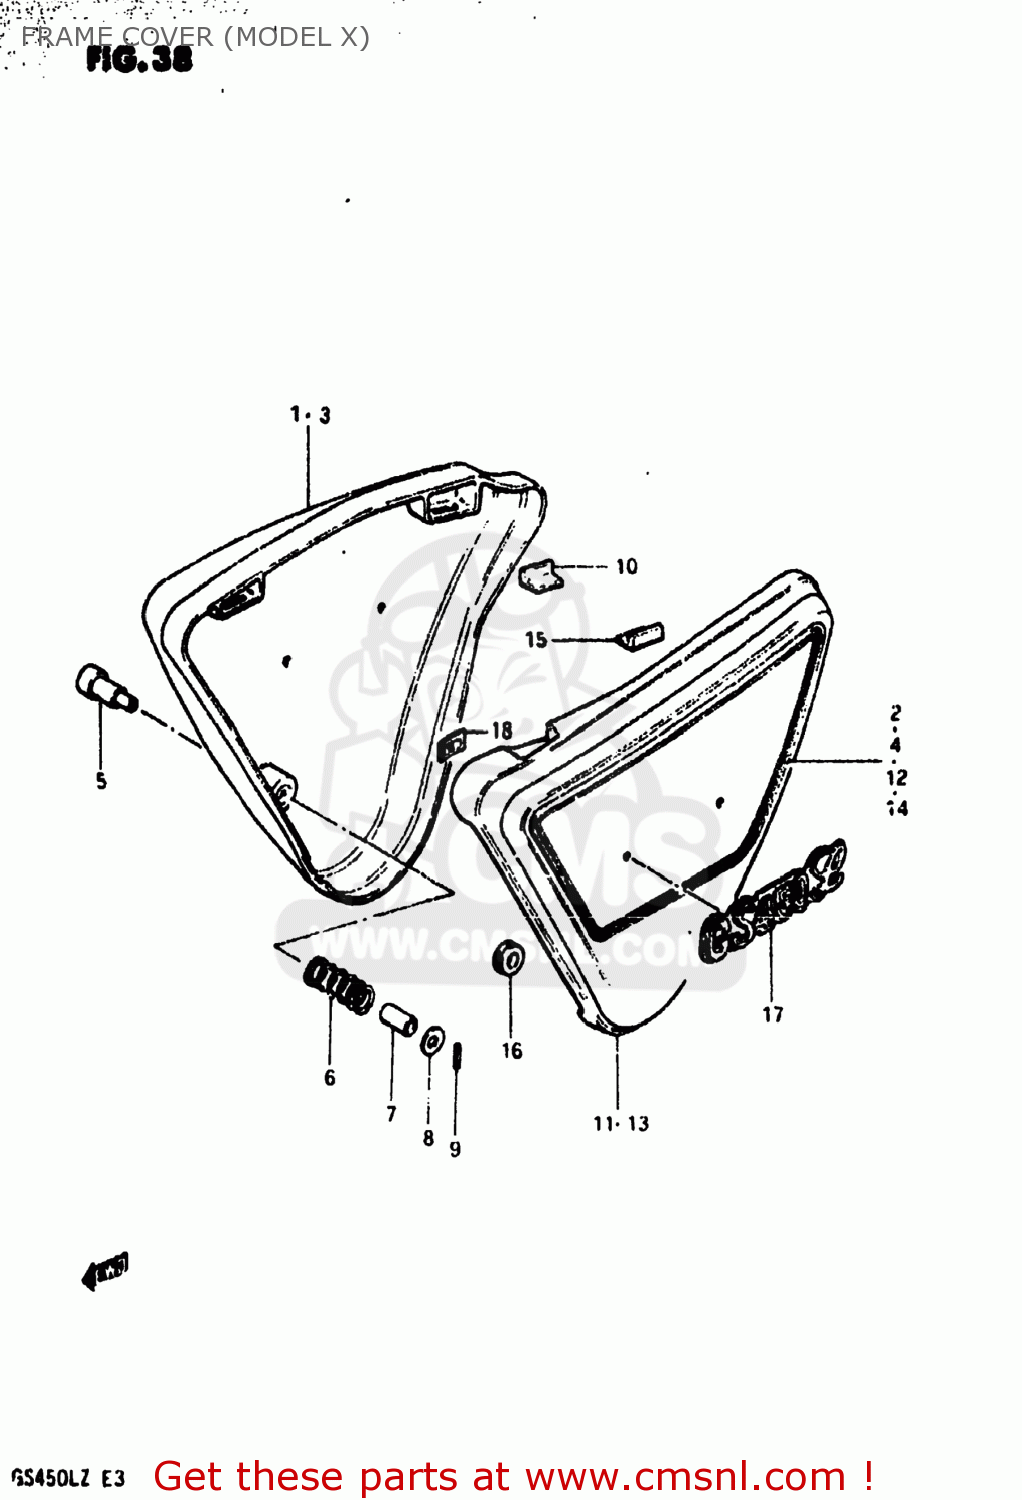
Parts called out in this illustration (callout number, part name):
1	COVER,FRAME,RIGHT
2	TAPE SET,FRAME COVER,RIGHT
3	COVER,FRAME,RIGHT
4	TAPE SET,FRAME COVER,RIGHT
5	KNOB,FRAME COVER
6	SPRING
7	SPACER(14.9X17.3X13.5)
8	WASHER (6.5X24X1.6)
9	PIN,SPRING(2.5X18)
10	CUSHION,FRAME COVER
11	COVER,FRAME,LEFT
12	TAPE SET,FRAME COVER,LEFT
13	COVER,FRAME,LEFT
14	TAPE SET,FRAME COVER,LEFT
15	CUSHION,FRAME COVER
16	CUSHION
17	EMBLEM
18	NUT
